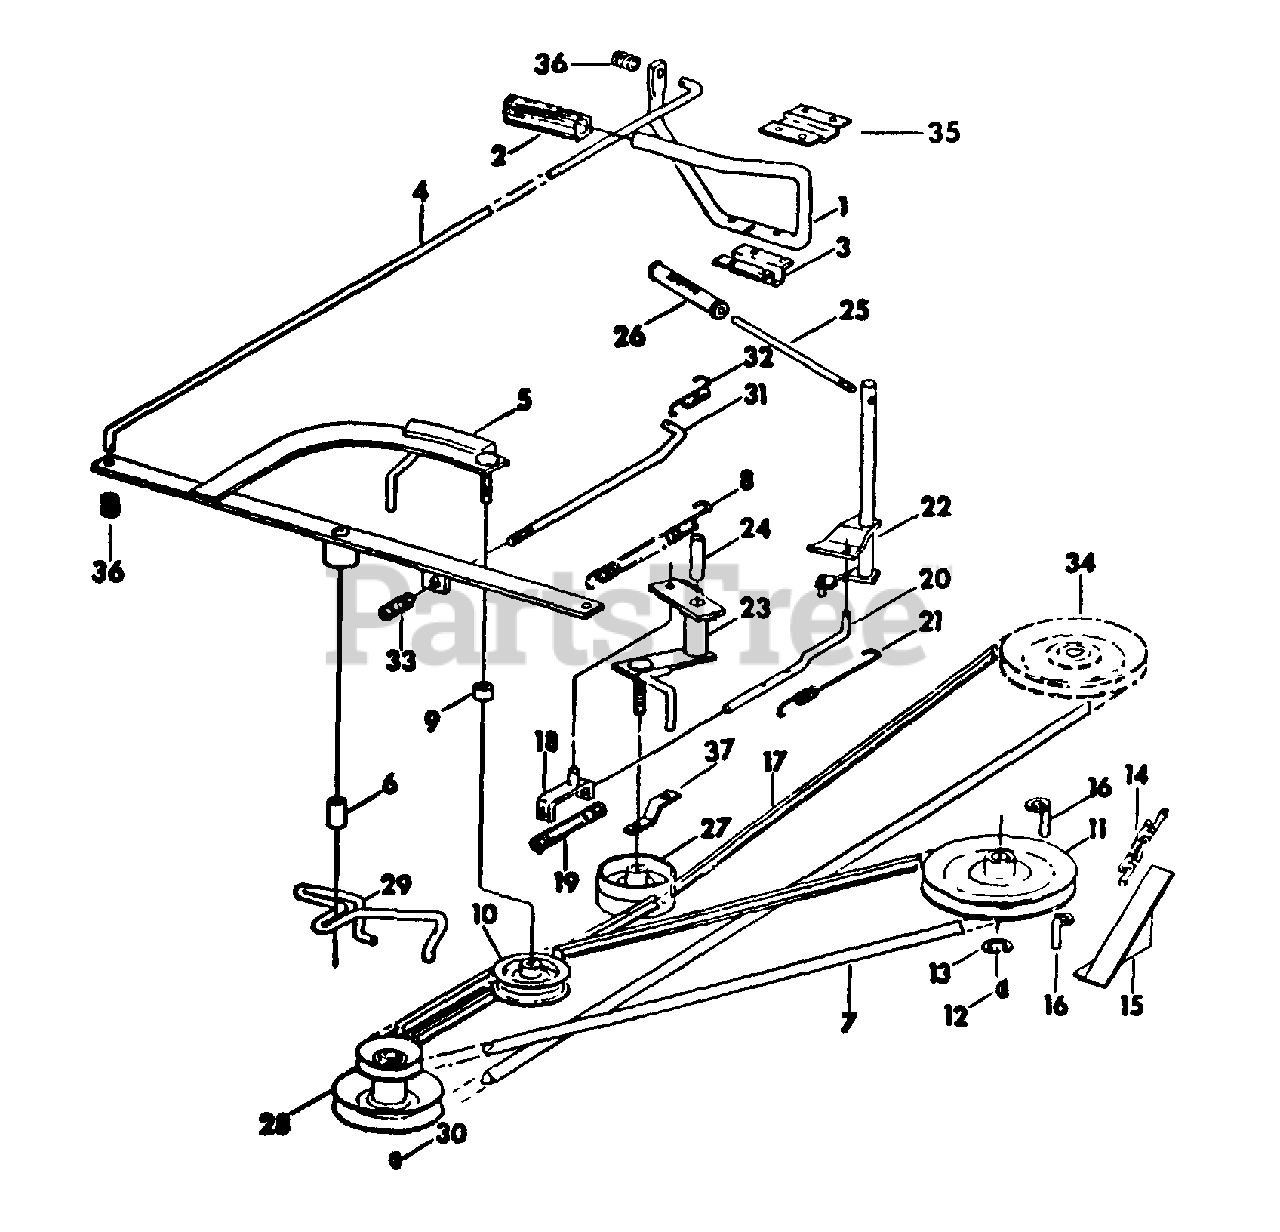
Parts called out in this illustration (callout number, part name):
1	PEDAL, CLUTCH AND BRAKE
3	CLAMP, PEDAL PIVOT
4	ROD, CLUTCH CONTROL
5	ARM ASSY. SHIFTER PIVOT
6	BUSHING, SHIFTER ARM
7	BELT, FORWARD DRIVE
8	SPRING, PEDAL RETURN
9	SPACER, 3/8 X 38 EXTRA STRONG PIPE
10	IDLER, BALL BRG
11	PULLEY, TRANSMISSION DRIVE
12	KEY, 3/16 X 3/4 WOODRUFF 9
13	RING, RETAINING
14	CHAIN, FINAL REDUCTION
15	SHIELD ASSY, DRIVE CHAIN
16	GUIDE, BELT
17	BELT, MOWER DRIVE
18	STRAP ASSY, IPTO
19	SPRING, IPTO
20	ROD, MOWER SHIFTER
21	SPRING, IPTO RETURN
22	LEVER ASSY, MOWER SHIFTER
23	LEVER ASSY, SHIFTER ARM
24	BUSHING, IPTO 8 HP
25	ROD, SHIFTER HANDLE
26	GRIP, SHIFTER HANDLE
27	PULLEY, MOWER SHIFTER IDLER
28	PULLEY, ENGINE AND MOWER DRIVE
29	GUIDE, BELT PTO AND FORWARD DRIVE
30	KEY, 5/32 X 5/8 WOODRUFF 6
32	SPRING, BRAKE RETURN
33	SPRING, COMPRESSION
34	PULLEY, CENTER
35	SPRING, CLUTCH PEDAL
36	SPRING, ANTI-RATTLE
37	RETAINER, MOWER BOLT
